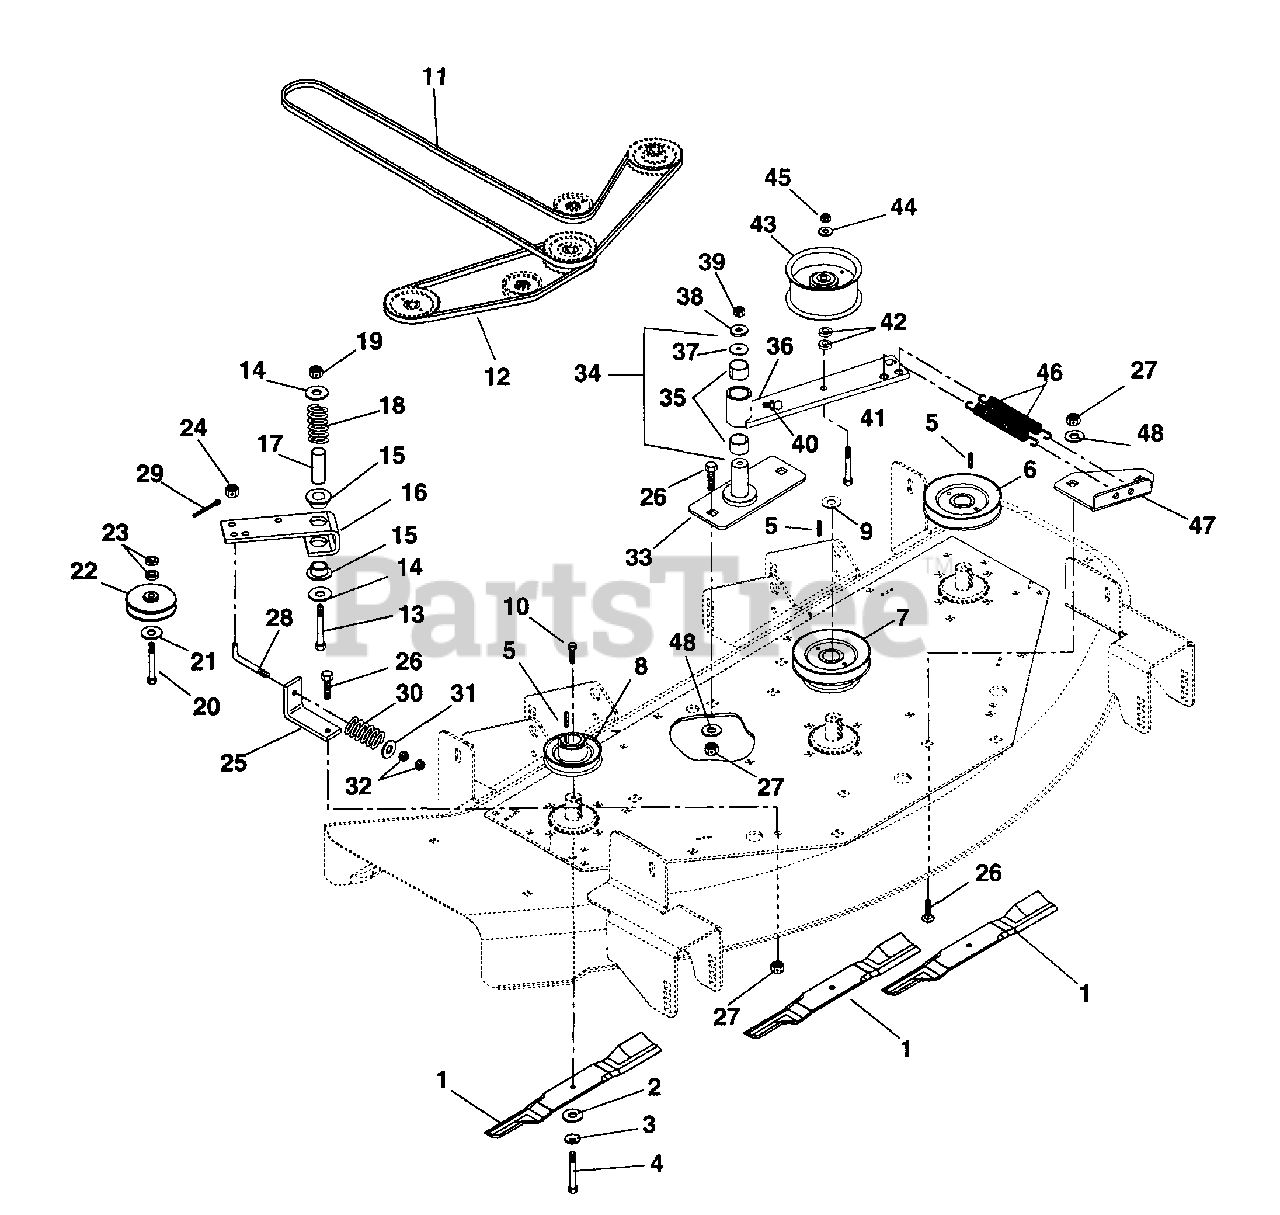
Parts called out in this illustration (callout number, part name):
1	BLD, 50 INCH MOWER
2	WSHR-FLT .640X1.75X.250 YWZC
3	WSHR-BLVL .669X1.535X.138
4	BLT-HEX .50-13X1.90 GR8 BLADE
5	KEY-SQ .25X1.0X.25 SAE 8630
6	WLDM'T,PLY-V 4.75X1.004
7	WLDM'T PLY-DBLV 4.75,3.50X1.00
8	WLDM'T, PLY-V 3.50X1.004 W/KEY
9	WASHER, CUPPED SERRATED, .375
10	BLT-HEX .38-16X1.00 YZ GR8
11	V-BELT, HA-RAW EDGE
12	V-BELT, HA-RAW EDGE
13	@BLT-RDHDSQNK .50-13X3.50 G5YZ
14	WSHR-FL-STL .531X1.250X.10 YWZ
15	BUSHING .406 X .750 X .188
16	ARM,IDLER PIVOT
17	SPACER .560X.750X2.437 ST
18	SG-COMP .085X.80X1.00 WLD36
19	@NUT-LK-CTR .50-13 YWZC
20	@BLT-HEX .38-16X2.00 GR5 YWZC
21	WSHR-FL-STL .375X1.125X.065YWZ
22	IDLER-V 3X.38
23	BUSHING .406 X .750 X .188
24	@NUT-LK-NYL .38-16 YWZC
25	BRKT,BELT TENSIONER
26	@BLT-HEX .50-13X1.25 GR5 YWZC
27	@NUT-LK-CTR .50-13 YWZC
28	ROD,IDLER
29	@PIN-CTR .09X.75 EXTPRSQCT YWZ
30	SG-COMP .125X.78X1.00 YWZ
31	@WSHR-FL-STL.406X.812X.065 YWZ
32	NUT-HEX-JAM .375-16 YWZC
33	WMT, IDLER PIVOT
34	ASSEMBLY, IDLER PIVOT ARM
35	BRG. 1.000 X 1.125 X .75
36	ASSEMBLY, IDLER PIVOT ARM
37	WSHR-FL-STL .380X1.50X.125YWZC
38	@WSHR-LK .38X.094 REG YWZC
39	@BLT-HEX .38-16X1.25 GR5 YWZC
40	FTG-LUBE .25-28X.256 YWZC
41	@BLT-HEX .38-16X2.75 GR5 YWZC
42	BUSHING .406 X .750 X .188
43	IDLER-FLAT 4.00X.38 (2.00 W)
44	WSHR-FL-STL .375X1.125X.065YWZ
45	@NUT-LK-CTR .38-16 YWZC
46	SG-EXT-.090X1.00X6.00
47	BRACKET, IDLER SPRING
48	@WSHR-FL-STL.50X1.25X.083 YWZC
